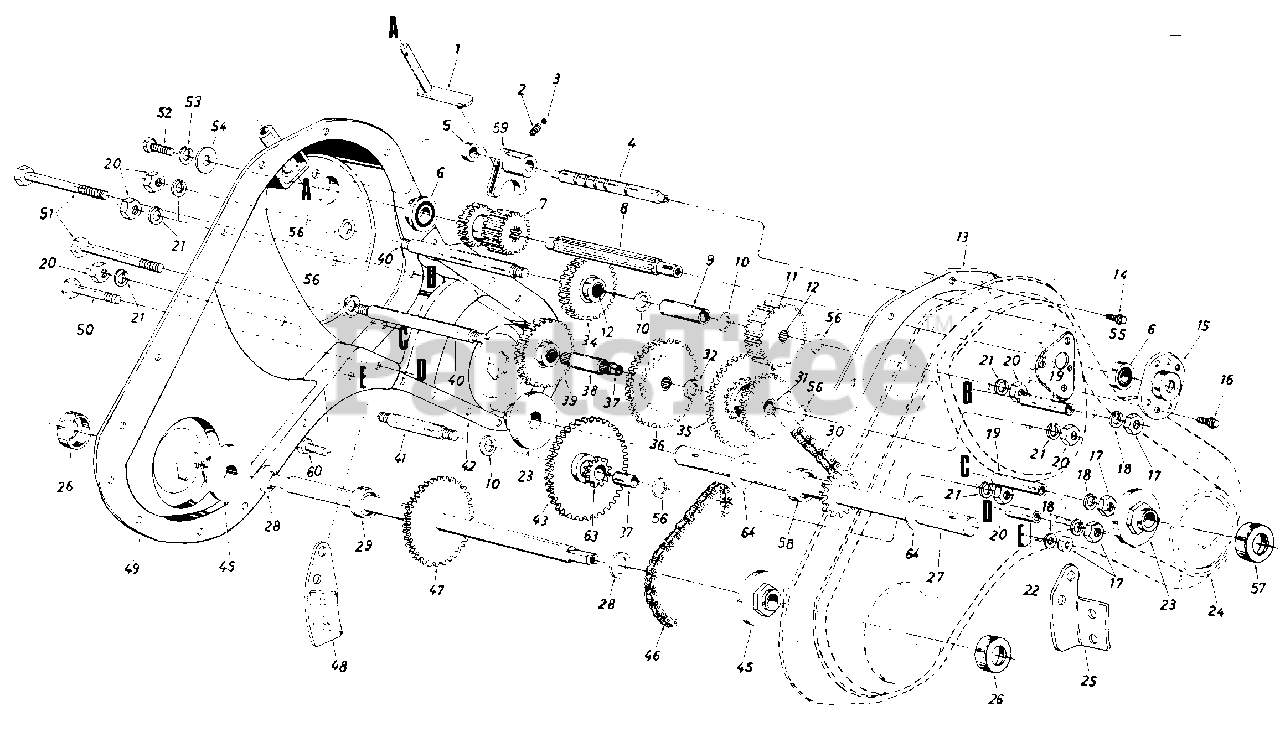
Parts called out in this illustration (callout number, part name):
1	Shifting Bracket Ass'y.
2	Compression Spring .50" Lg.
3	Ball Detent .250" Dia.
4	Detent Shaft 1/2" Dia.
5	Spacer .505" I.D. x .88" O.D.
6	Ball Brg. .62" I.D. x 1.38"
7	Spur Gear 16T
8	Input Spline Shaft 7/8
9	Spacer .657" I.D. x 2.85" Lg.
10	Fl-Wash. .640" I.D. x 1.24"
11	Spur Gear 30T 7/8" I.D.
12	Needle Bearing 5/8" I.D.
13	Gasket Trans. Hsg.
14	Hex Wash. S-Tap Scr. 1/4-20 x .50" Lg.
15	1-3/8" Dia. Bearing Housing
16	Hex TT-Tap Scr. 1/4-20 x .75"
17	Hex Nut 5/16-18 Thd.
18	L-Wash. 5/16" I.D.
19	Spacer 1.56" Lg.
20	Hex Nut 7/16-20 Thd.
21	Bell-Wash. .45" I.D. x 1.0"
22	Spacer 1.015" Lg.
23	Tine Shaft Brg. 1.002 x 2.50
24	Trans. Housing Ass'y. L.H.
27	Tine Shaft Ass'y. 1.00" O.D.
28	Fl-Wash. .75" I.D. x 1.5" O.D.
29	Spacer .75" I.D. x .50" Lg.
30	Chain #50 5/8 Pitch x 52 Links Endless
31	Needle Bearing 5/8" I.D.
32	Fl-Wash. 5/8" I.D.
34	Spur Gear 30T 12/16" I.D.
35	30/44T Gear Ass'y. Comp.
36	Spur Gear 44T
37	Sleeve Bearing
38	Gear Hub 3/4" I.D. x 3.0" Lg.
39	Spur Gear 30T 1.0" I.D. x 1/2" W
40	Jack Shaft 5/8" Dia. x 5.0"
41	Jack Shaft 5/8" Dia. x 2.38"
45	Wheel Brg. .752 x 2.50
46	#420 Chain 1/2 Pitch x 50 Links Endless
47	Wheel Shaft Ass'y. 15.6"
51	Hex Bolt 5/16-18 x 2.50"
52	Hex Bolt 1/4-20 x .62" Lg.
53	L-Wash. 3/8" I.D.
54	Fl-Wash. 1/4" I.D. x .93" O.D.
55	Gear Positioner Bracket
56	Fl-Wash. 7/16" I.D. x 1-3/8"
57	Dust Cover Ass'y. 1.0" Shaft
58	Spacer 1.0" I.D. x 2.0" O.D.
59	Shifting Fork
60	Hex Bolt 5/16-18 x .75" Lg.
63	10T Sprocket Ass'y.
64	Thrust Wash. 1.030" I.D. x 1.62" O.D.
